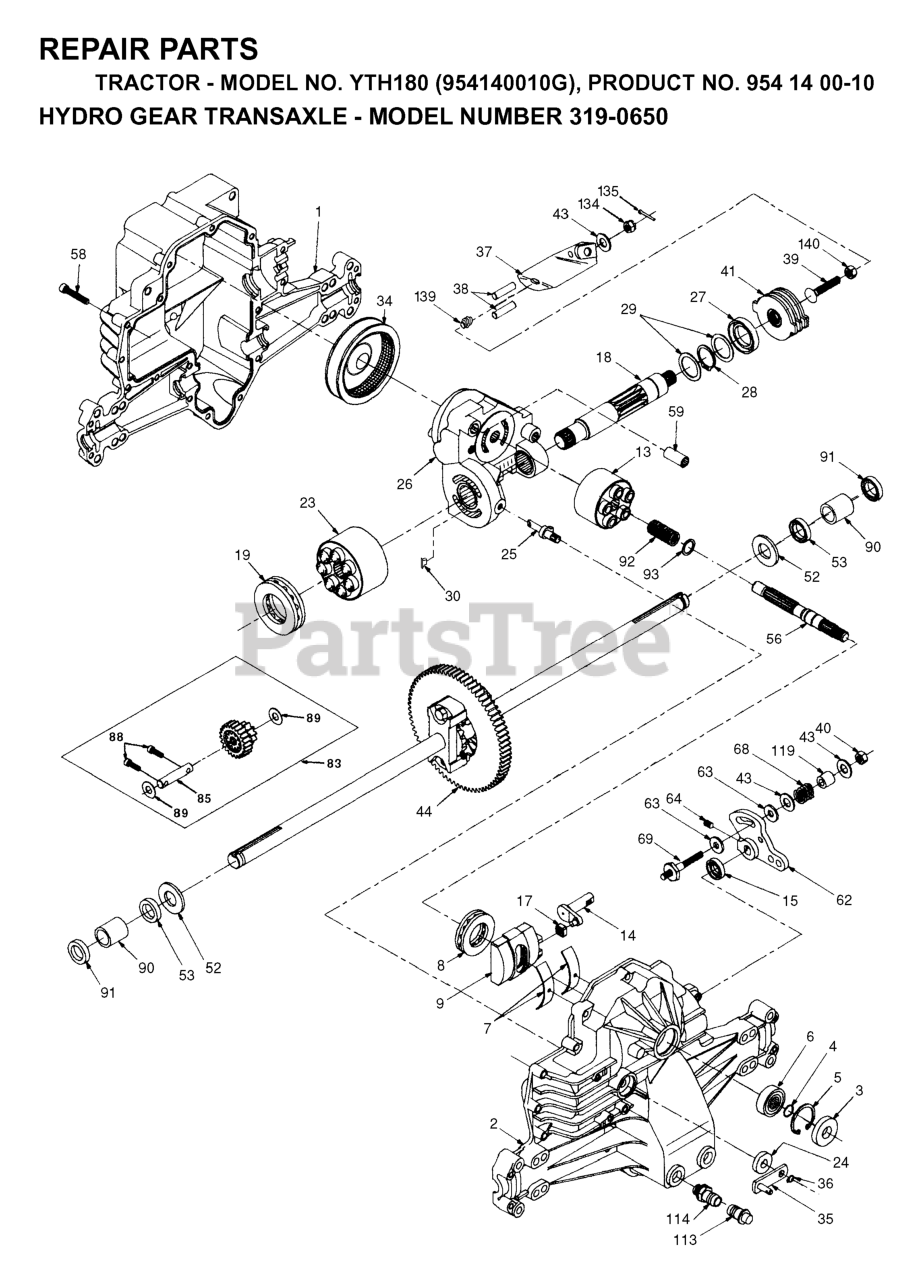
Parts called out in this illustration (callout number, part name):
1	LOWER HOUSING
2	HOUSING UPPER 70255
3	SEAL.LIP.H-G.(9008000-0128)
4	RING RETAINING 2003016
5	RING.RETAINING.(2003052)
6	BALL BEARING
7	CRADLE BEARING
8	BEARING, THRUST 50551
9	SWASHPLATE (2003087)
13	BLOCK, CYL ASSY
14	TRUNNION ARM
17	SLOT GUIDE
18	SHAFT, MOTOR
19	BEARING, THRUST 50552
23	BLOCK, CYL ASSY
25	BYPASS ACTUATOR
26	CENTER SECTION ASS'Y KIT
28	RETAINING RING
34	ELEMENT, OIL FILTER
35	BYPASS ARM
36	RETAINING RING 44870
37	ACTUATING ARM
38	ACTUATING PIN 44891
39	BOLT 5/16-24 X 1-3/4
40	LOCKNUT, HEX 5/16-24
41	BRAKE ROTOR 70135 HYDRO-GEAR
43	WASHER .34X.88X.06.44130
44	KIT SVC DIFFRENTIAL 70130
52	WASHER.HYDRO-GEAR 44875
53	SEAL.HYDRO.53901
56	SHAFT.INPUT.50005
58	BOLT #44876
62	CONTROL ARM 50254
63	DAMPENER PUCK
64	SCREW.SET.50018
68	SPRING HELICAL COMP 50277
69	STUD 5/16-24 50284
83	JACK SHAFT ASSY
89	WASHER 50132
90	SLEEVE.BEARING 50118
91	RP SEAL, WIPER
92	SPRING 2003014
113	CAP, VENT ASSY
114	O-RING KIT 70110
119	SPACER.HYDRO GEAR 50278
134	NUT.CAS.HYD.44142
135	ID DOT HYDD
139	SPRING, COMPRESSION 50431
140	NUT, HEX 5/16-24
